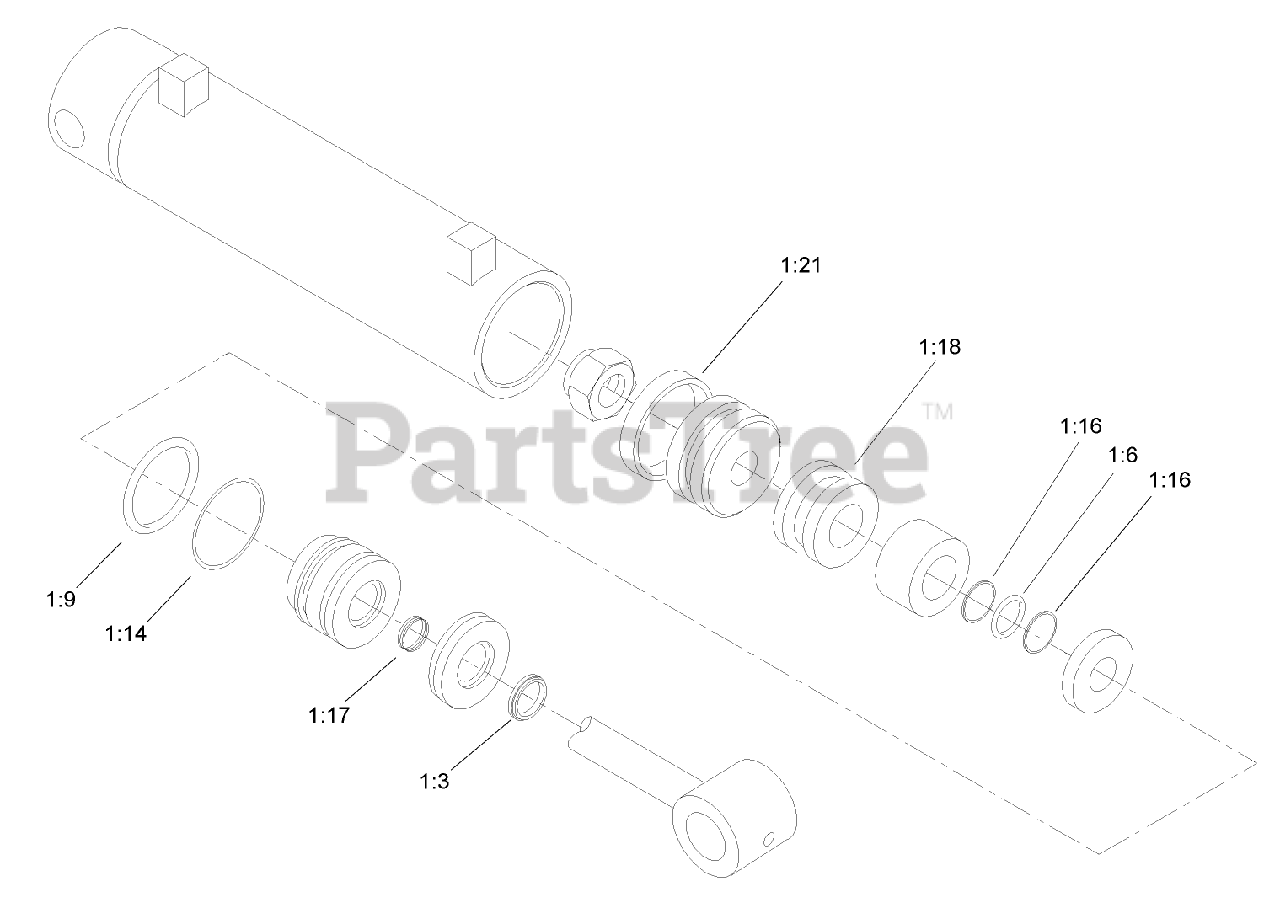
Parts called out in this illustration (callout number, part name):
1	CYLINDER SEAL KIT
1:3	Seal-Wiper
1:6	Seal-Dust
1:9	Seal-Dust
1:14	RING-BACKUP
1:16	RING-BACKUP
1:17	PACKING ASSEMBLY
1:18	PACKING ASSEMBLY
1:21	RING-WEAR
